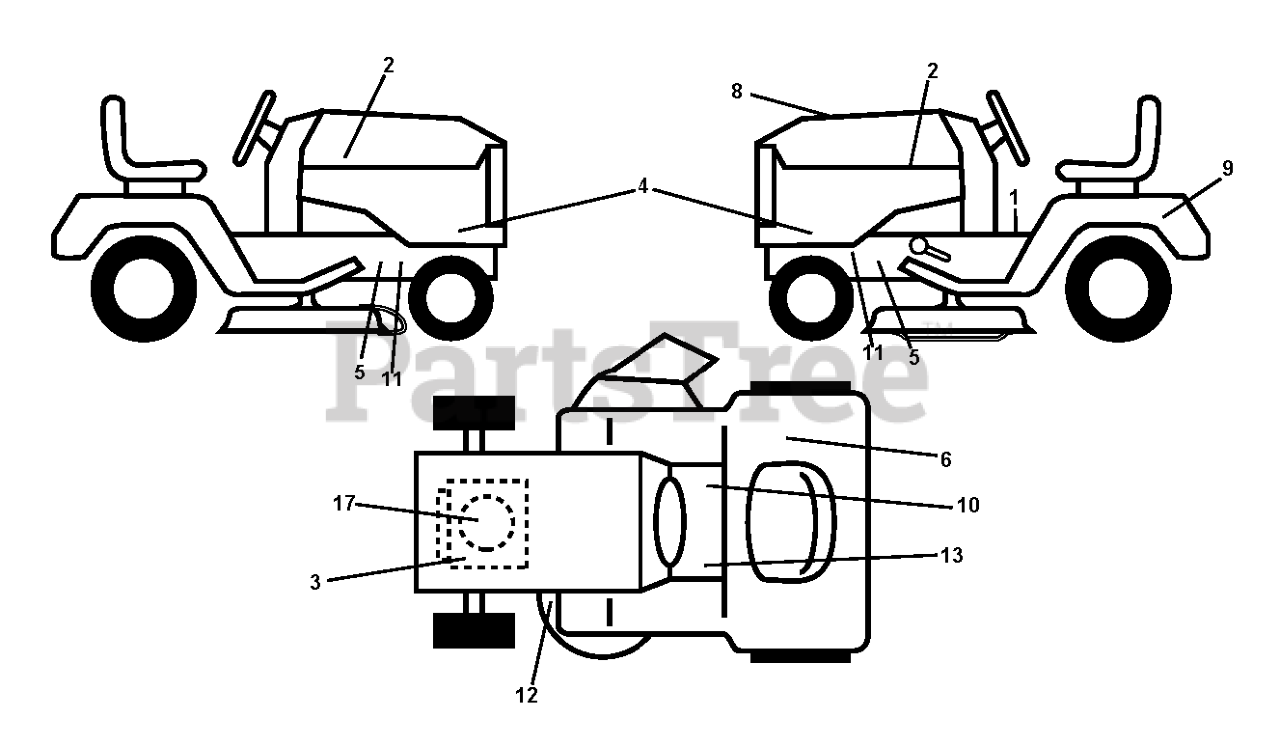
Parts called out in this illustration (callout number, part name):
1	LABEL
2	DECAL.HOOD.LOGO.ORANGE.HUSQVAR
3	DECAL
4	Decal, Hood Panel
6	Decal, Fender 100 DB/CE
8	Decal, Rpl
9	DECAL BTRY SYMBOLS
10	DECAL PARK BRAKE
12	Decal, Mower V-Belt Schematic
13	DECAL
